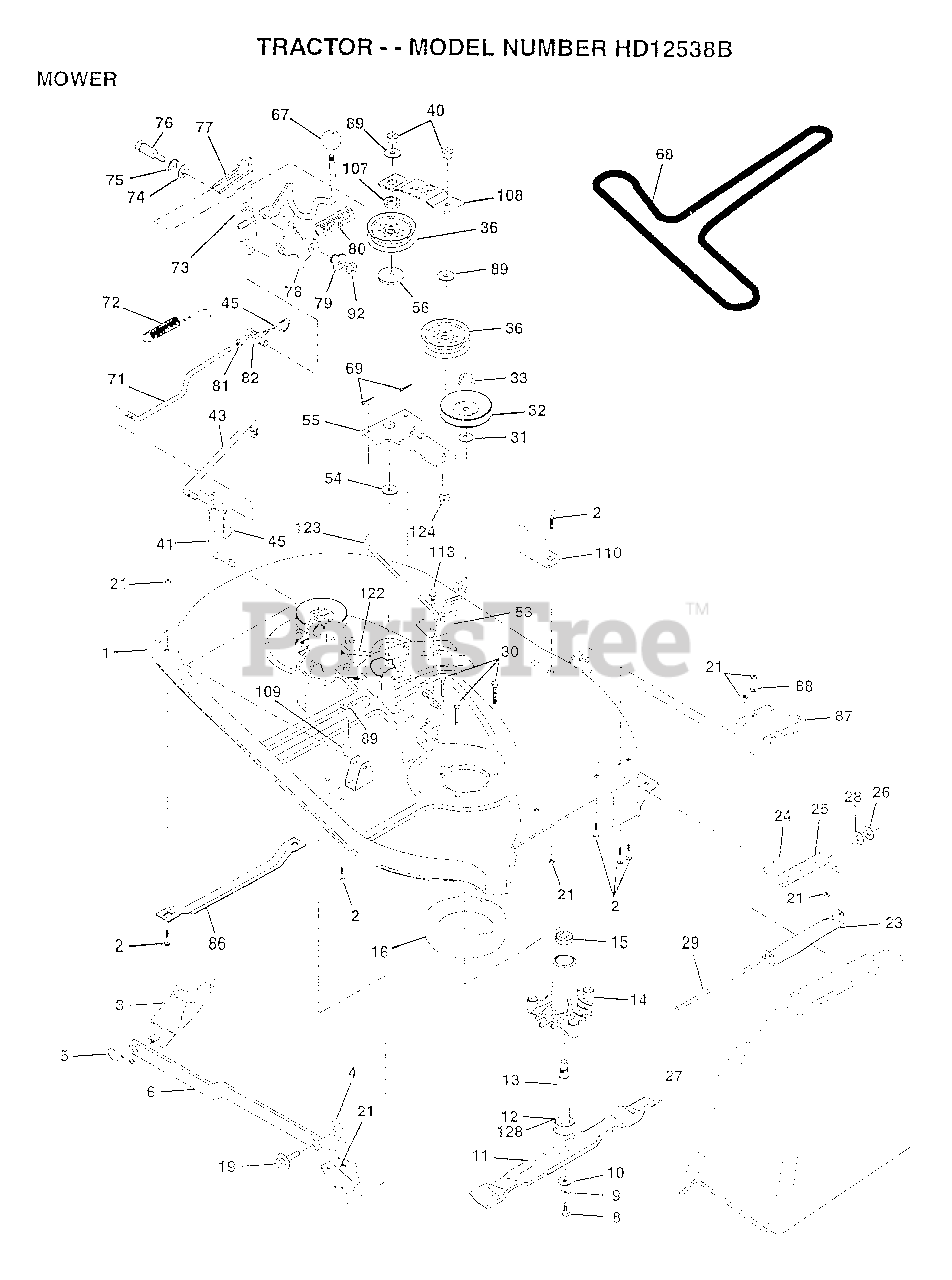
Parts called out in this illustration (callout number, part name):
2	BOLT
3	BRKT ASM SWAY BAR
4	BRKT DECK SW BAR
8	BLADE BOLT
10	WASHER.HARD.BLADE
11	"BLADE.38"" HIPERF"
12	BEARING.BALL
14	HSG ASM MANDREL
15	BEARING
16	STRIPPER RND MWR
19	BOLT SHD 5/16-18
23	BRKT DEFLECTOR
24	CAP-SLEEVE LT
25	SPRING TORSION
26	NUT PUSH M
27	DEFLECTOR-SHLD T
28	WASHER
29	ROD-HINGE T
31	WASHER
32	PULLEY.MANDREL.38
36	FLAT IDLER PULLEY
41	PIVOT ROD
43	CLUTCH ROD SECOND
45	RETAINER M
53	BRAKE ASM
54	HARDENED WASHER
55	IDLER ARM ASSY
56	SPACER RETAINER
67	KNOB T(3/8 HOLE)
68	BELT.V.T-PATH
71	ROD CLUTCH 38/42
72	RETURN SPRING
73	CLUTCH ARM SECOND
74	WASHER
75	RING
76	SHOULDER BOLT
77	SPRING KEEPER
78	LEVER ASM-CLUTCH
79	BUSHING
80	SPRING.CLUTCH.MWR
81	NUT
82	TRUNION ADJ
86	RUNNER-LH M
87	RUNNER RH
88	WASHER M
89	WASHER GT
92	NUT
107	RETAINER SPACER
108	IDLER ARM STIFF
109	BOLT
110	UPSTOP DECK FT 38
113	SCREW
122	BRAKE ROD LH
123	BRAKE ROD RH
124	BOLT
128	WASHER.FELT.
